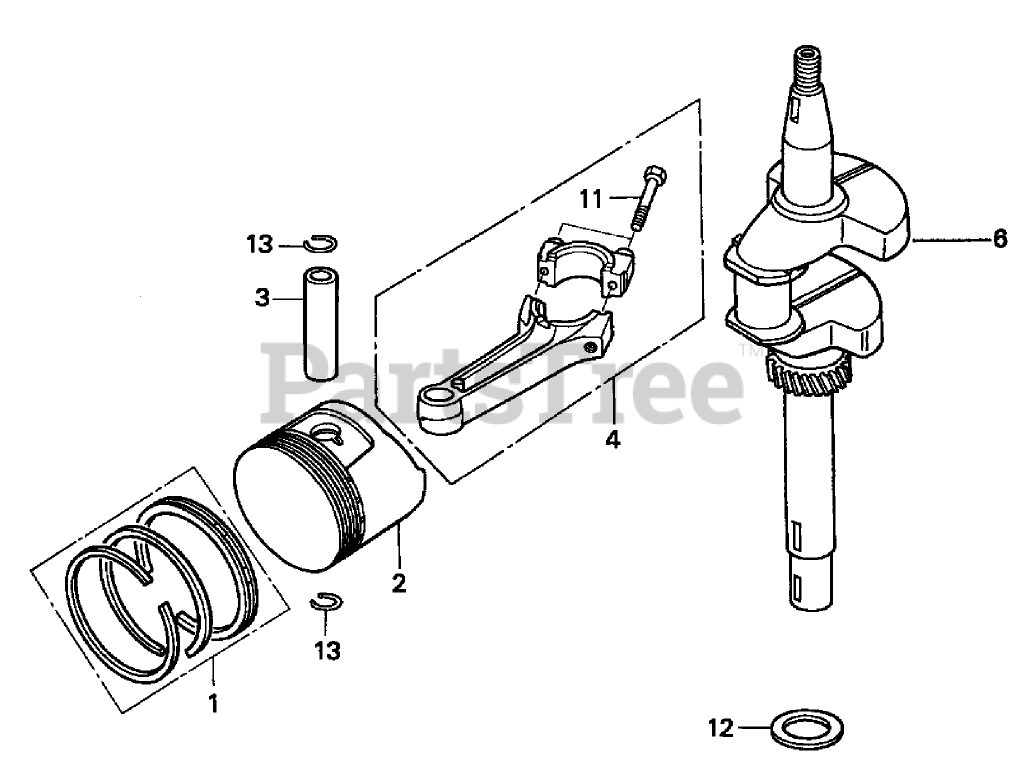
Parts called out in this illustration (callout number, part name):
1	RING SET-PISTON (STD)
2	Piston (STD)
3	Pin-Piston
4	CONNECTING ROD ASM
6	CRANKSHAFT
11	BOLT-ROD, CONNECTING
12	WASHER-THRUST (25.6 mm)
13	CLIP-PIN, PISTON (18 mm)
